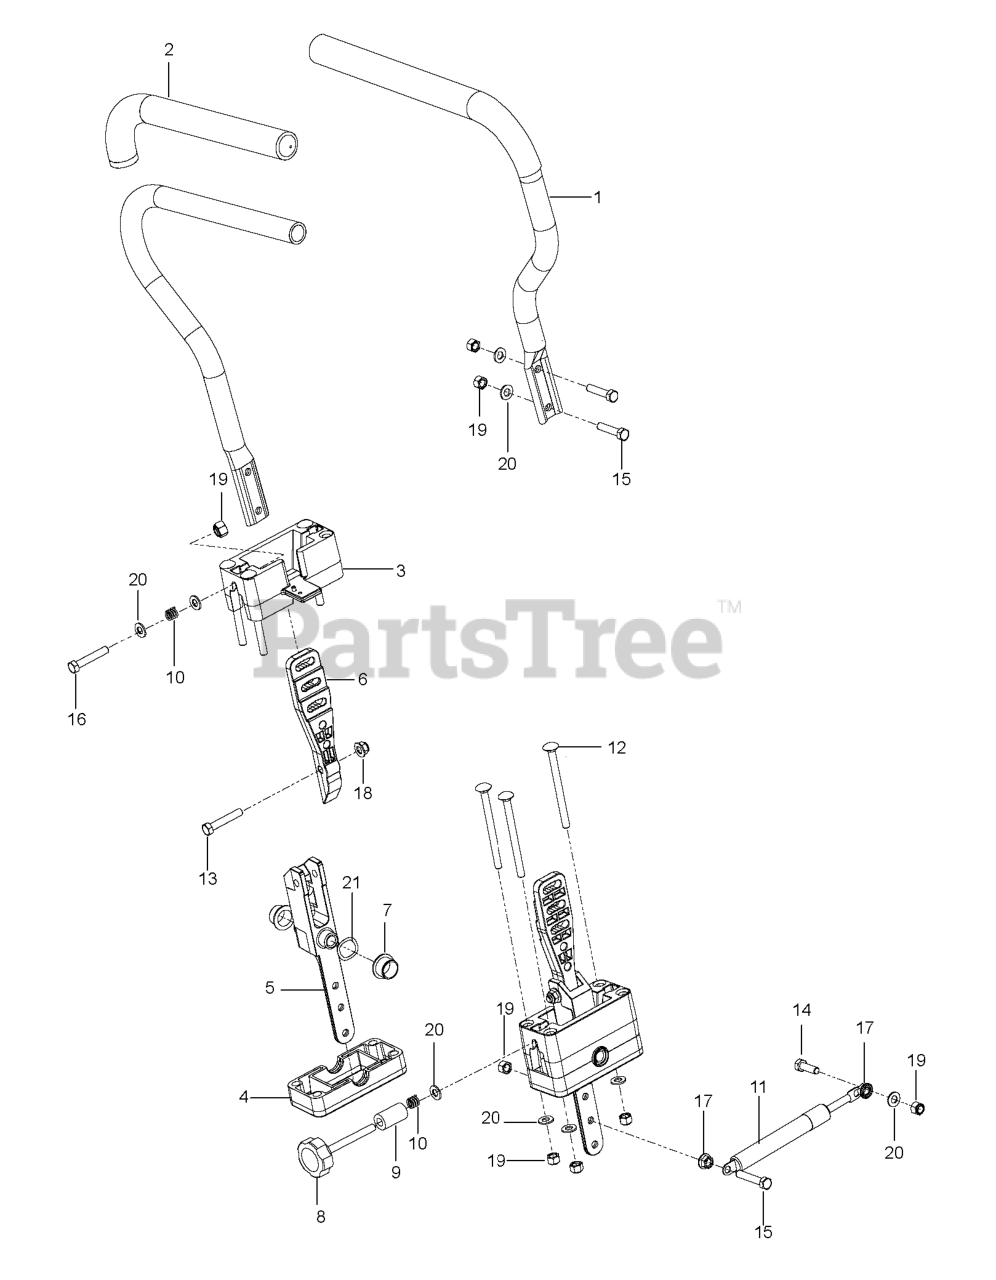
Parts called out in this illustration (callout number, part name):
1	ASSEMBLY, DRIVE LEVER
2	GRIP, DRIVE LEVER
3	BLOCK, UPPER
4	BLOCK, LOWER
5	PIVOT.SECTION.DRIVE.CONTROL
6	MOUNT, DR CNTRL HANDLE
7	BEARING, FLANGE
12	RHSNB 5/16-18 X 4 GR 5 ZD
13	HCS 5/16C X 1 3/4
14	HCS 5/16C X 1
15	CAPSCREW 5/16 X 1/1/2 HEX HEAD
16	HCS 5/16-18 X 2 TPBLT GR 5 ZD
17	NUT 5/16C WHIZ
18	5/16-18 NYLOC FLANGE NUT
19	NUT 5/16 NYLOC
20	FLAT WASHER 5/16 SAE
21	WASHER, .825 X 1.087, WAVE
